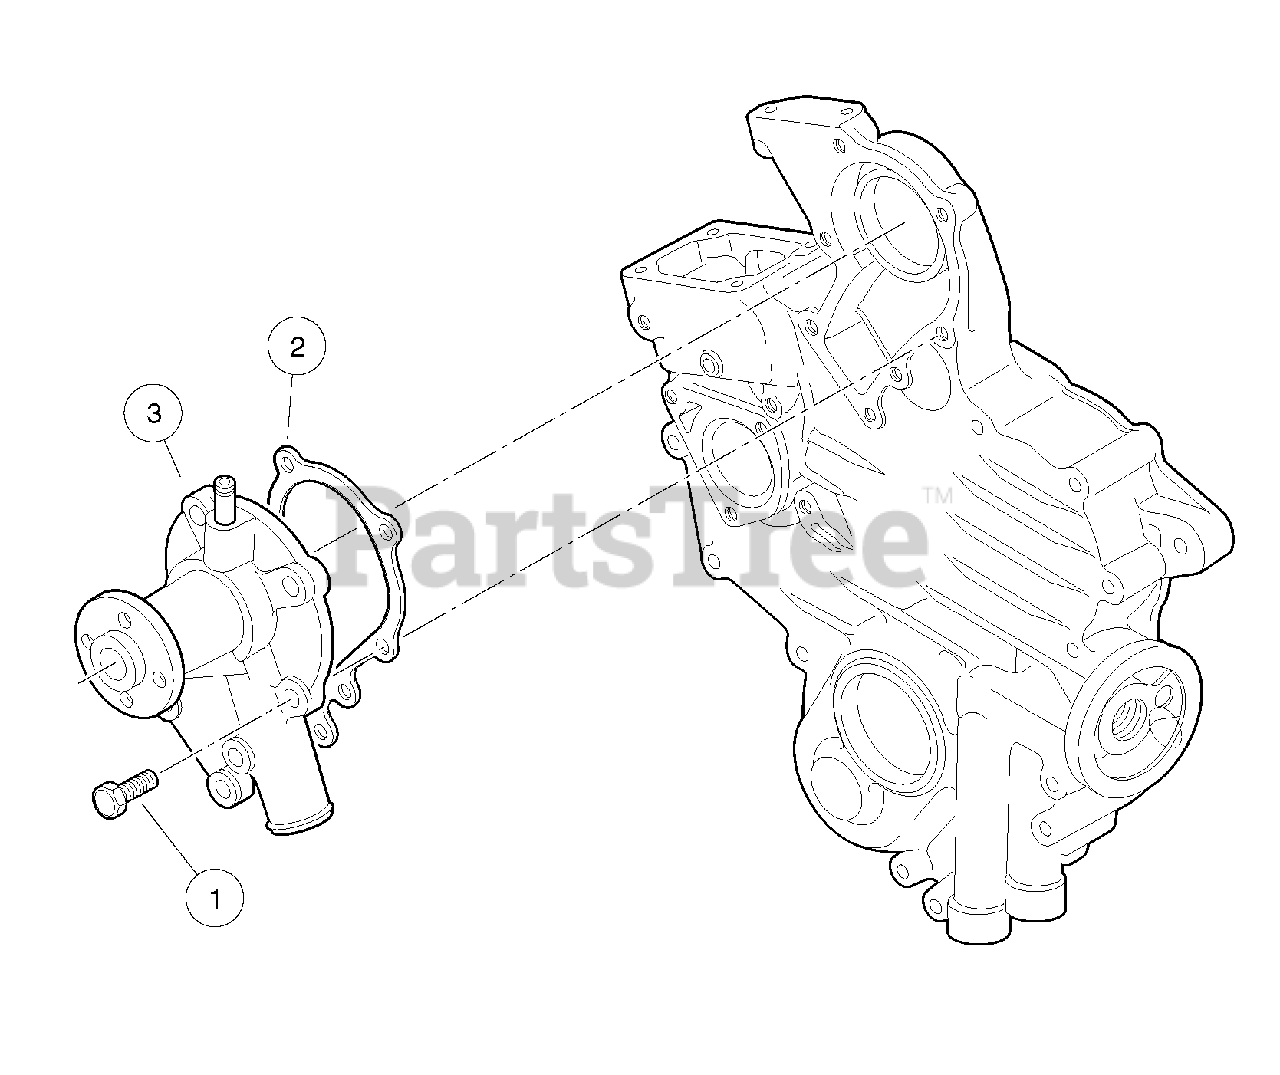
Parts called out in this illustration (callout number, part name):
1	Bolt, M6 X 1 X 22
2	Gasket, Water Pump, D722
3	Water Pump Assembly
